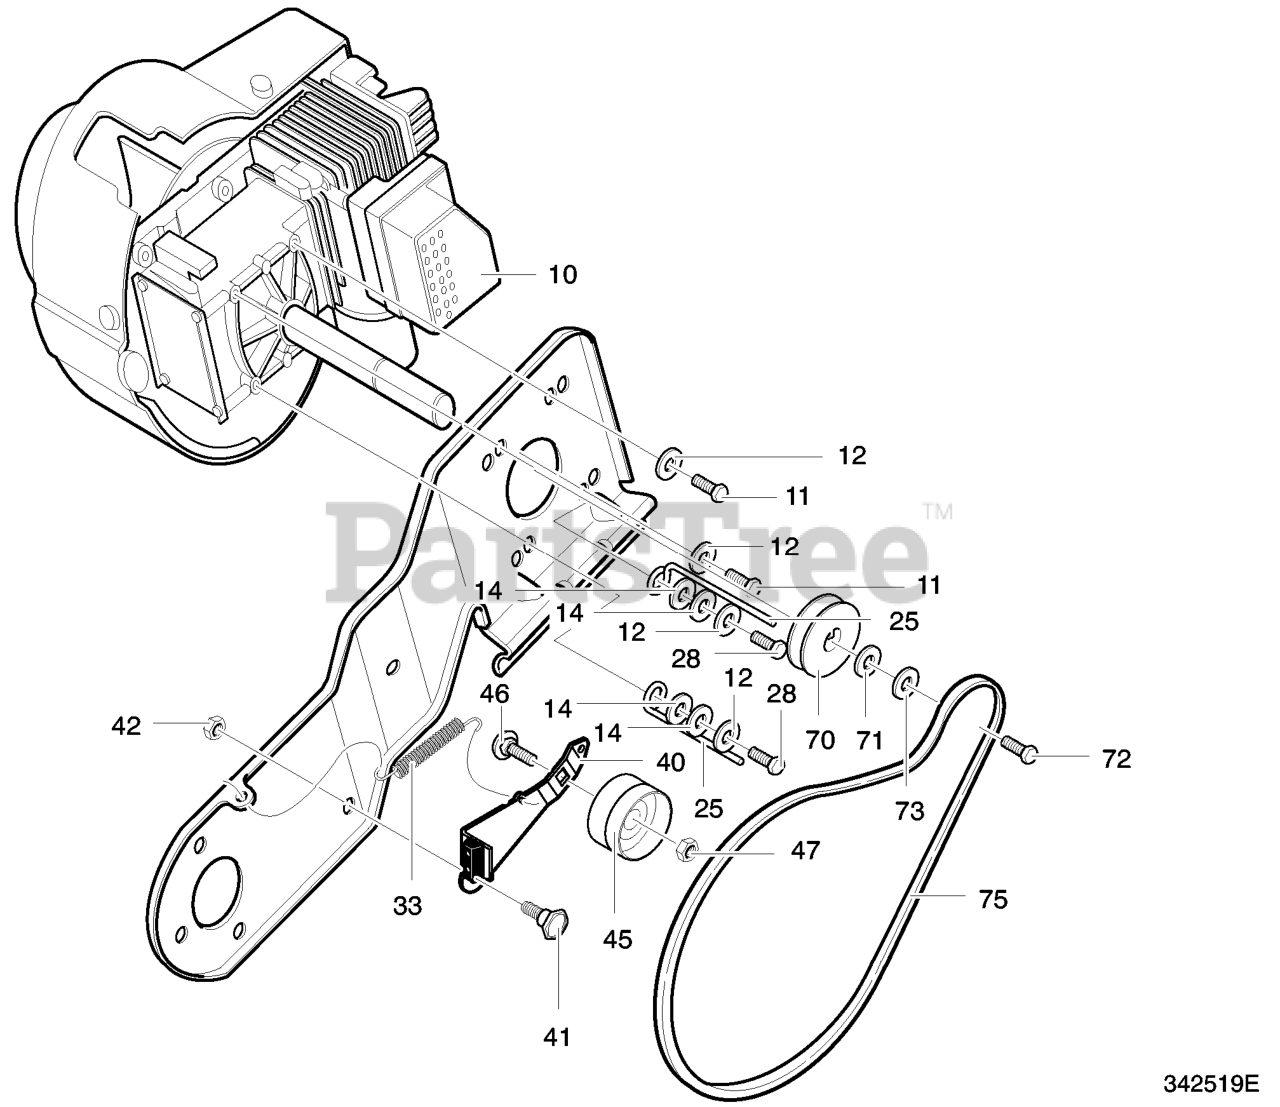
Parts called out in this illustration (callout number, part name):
10	ENGINE
11	SCREW, 5/16-18 x 0.75
12	WASHER, SPLTLK
14	WASHER, FLAT
25	GUIDE, BELT
33	SPRING, IDLER BRAKE
40	ASSY, IDLER BRAKE ARM
42	NUT, 5/16-18
45	PULLEY, IDLER
46	BOLT, CARRIAGE
47	NUT
70	PULLEY, ENGINE
71	WASHER, BELLEVELLE
72	SCREW, 5/16-24 x .75
73	WASHER, SPLTLK
75	BELT, V 3L 34.8"
